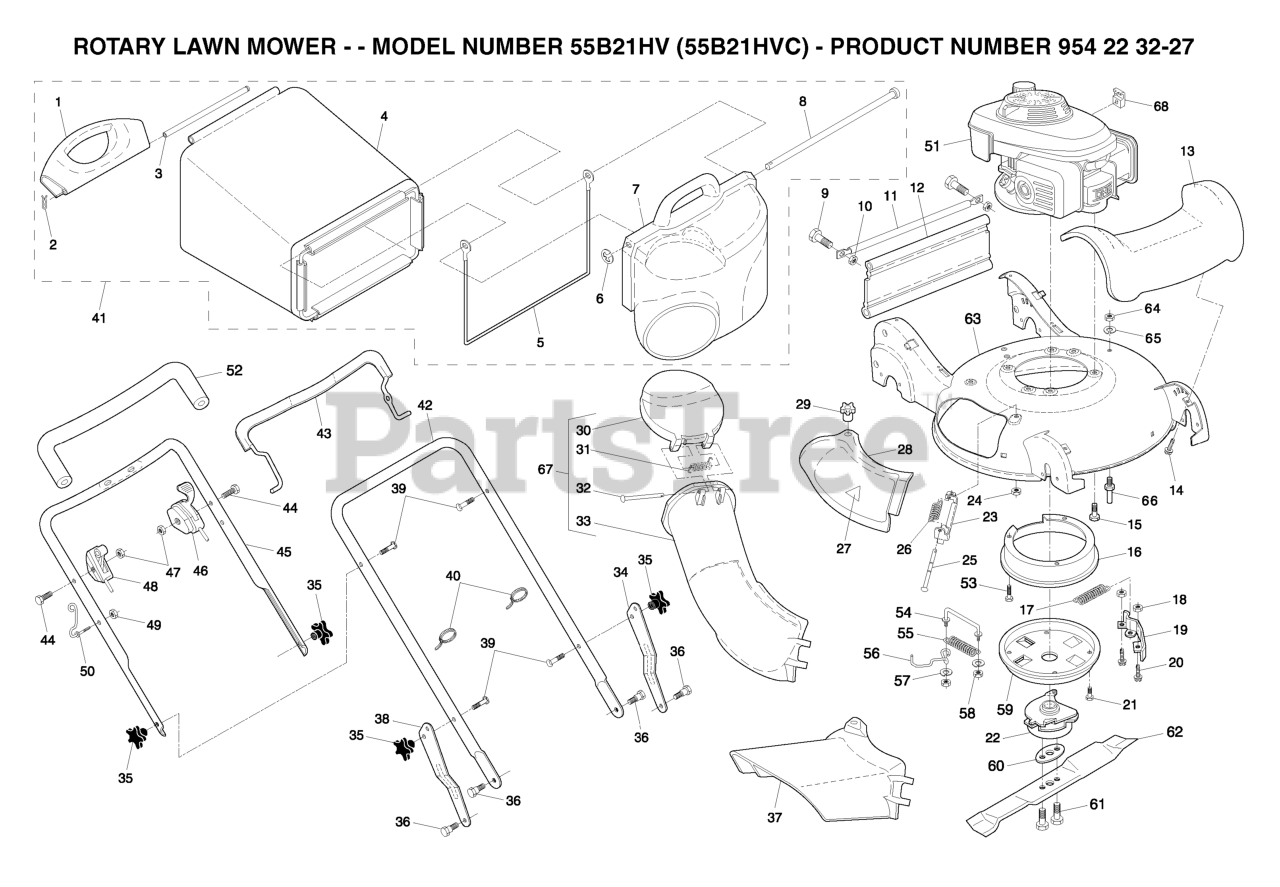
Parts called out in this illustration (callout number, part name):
1	HANDLE.GRASSBAG.REAR.H-GRAY
2	COTTER PIN (3 2)(2 2MC)
3	ROD.REAR.HANDLE.YELLOW
4	GRASSBAG
5	FRAME, GRASSBAG
7	DOOR, GRASSBAG
8	ROD, PIVOT
10	LOCKNUT.NYLOC.1/4-20
11	TUBE, REAR SKIRT
12	SKIRT, REAR
13	COVER, FRONT
14	SCREW
15	BOLT 3/8-16X1-1/8
16	COVER.BELT.BBC.AW.TOP
17	SPRING.BBC
18	NUT T
19	BRAKE, CLUTCH
20	BOLT
21	TAPPING SCREW
23	BRACKET.ASM.HINGE
24	LOCK NUT
25	ROD.HINGE.1/4"3.82"
26	SPRING.MULCH.DOOR
27	DECAL HYT
28	MULCHER DOOR
29	KNOB.MULCH.DOOR
30	CHUTE.DOOR.21.HV.H-GRAY
32	ROD.HINGE.1/4"3.82"
33	DISCHARGE CHUTE PLASTIC
34	ADJUSTMENT BRACKET, LOWER LH
35	KNOB.HANDLE.STAR.HUSQ.GRAY
36	SHOULDER BOLT
37	GUARD.CLIP.ON.21.HV.GRAY
38	BRACKET.ADJ.LOWER.HDL.RT.GREY
39	HANDLE BOLT
40	TIE GUIDE
41	GBAG.ASM.21.HV"CROWN"BLUE
42	HANDLE.LOWER.GREY
43	BAIL
45	HANDLE.ASM.UPPER.W/GRIP
46	BLADE BRAKE CONTROL
48	THROTTLE CONTROL
50	GUIDE.ROPE.WALK.MOWER
52	GRIP.HANDLE.FOAM.WIDE.(1 SIDE)
53	BOLT 3/8-16X1-1/8
54	LINK.TORQUE.BBC
55	SPRING.LINK.BBC
56	BELT KEEPER
59	BELT COVER, LOWER
61	BOLT.BLADE.BBC
62	BLADE.21".BBC
64	NUT LOCK FLG 3/8-16 UNC
65	LOCKWASHER
66	STUC.GUIDE.BELT.RWGD
67	CHUTE.LOWER.ASM.WALK.MOWER
68	BRACKET.THROTTLE
